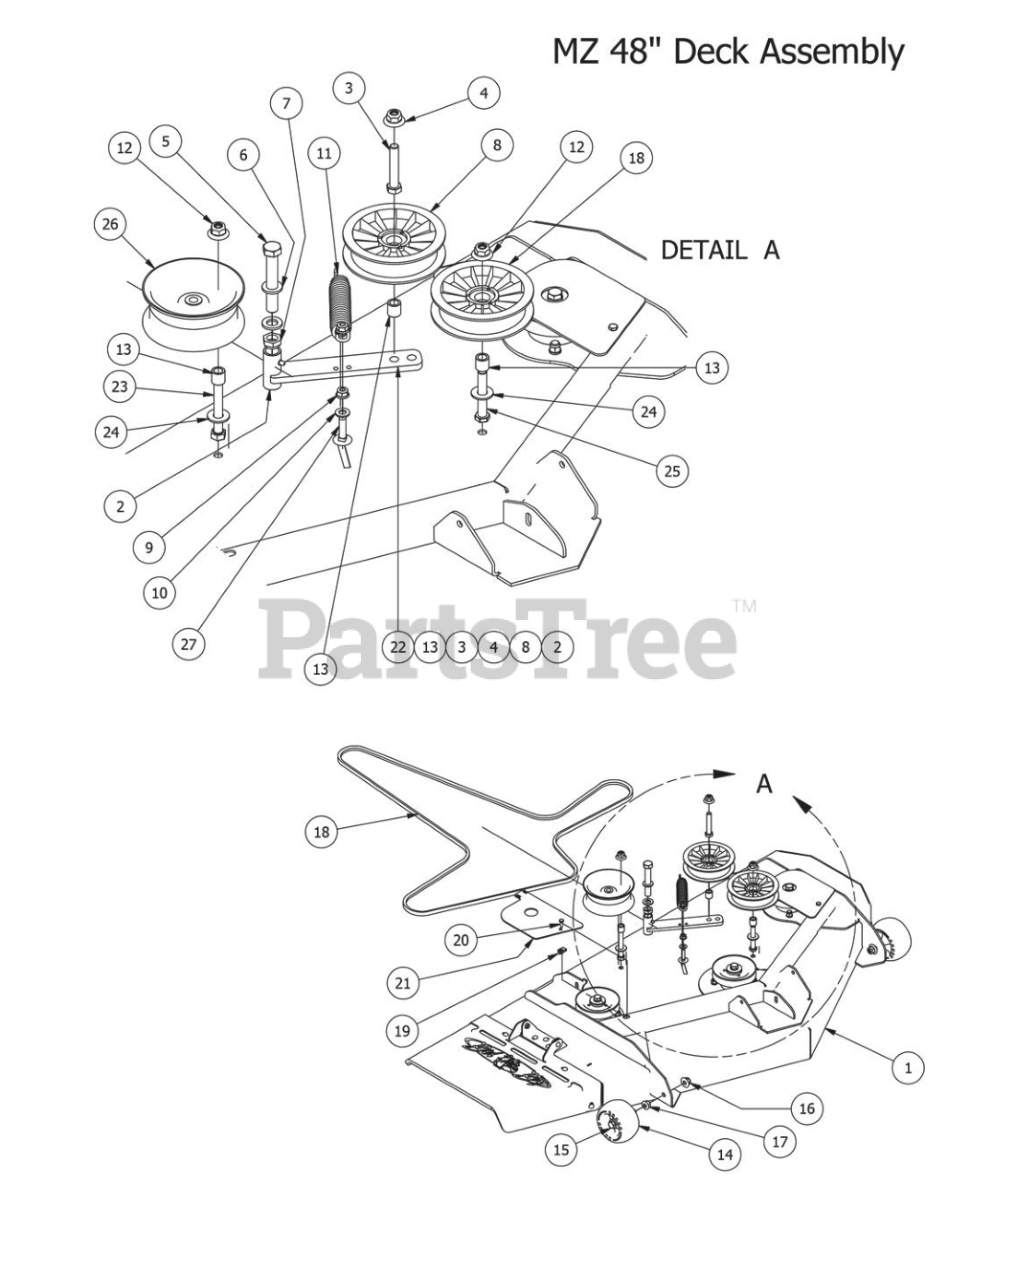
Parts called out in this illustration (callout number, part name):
1	48 MZ Deck
2	Deck Idler arm
3	1/2" x 2 3/4" Hex Bolt
4	1/2-13 Nylon Flange Nut-Orange
5	5/8" x 4" Hex Bolt
6	.635 ID Plastic Washer
7	5/8" Nylock (1/2 Jam)
8	Plastic Idler Pulley
9	3/8" Nylock Flange Nut
10	3/8" Flat Washer
11	Deck Idler Spring
12	1/2-13 Nylon Flange Nut-Orange
13	3/4 OD x 1/2 ID x 3\4 Length
14	Deck Wheel
15	1/2 x 3 1/2 Flange Bolt Grade 8
16	1/2-13 Nylon Flange Nut-Orange
17	1/2-13 Hex Flange (GR.G) ZC
18	B128 Deck Belt
19	1/4-20 Cage Nut
20	1/4" x 3/4" Hex Bolt
21	MZ Pulley Cover 48"
22	Parts 2,3,4,8,13 make up the deck idler assembly
23	1/2-13 x 3 1/2 GR 5 Hex Bolt
24	1/2" Washer (Grade 8)
25	1/2-13 x GR 5 Hex Bolt Zinc
26	5 3/4" Deck Idler Pulley
27	3/8 x 1-1/2 Carriage Bolt
